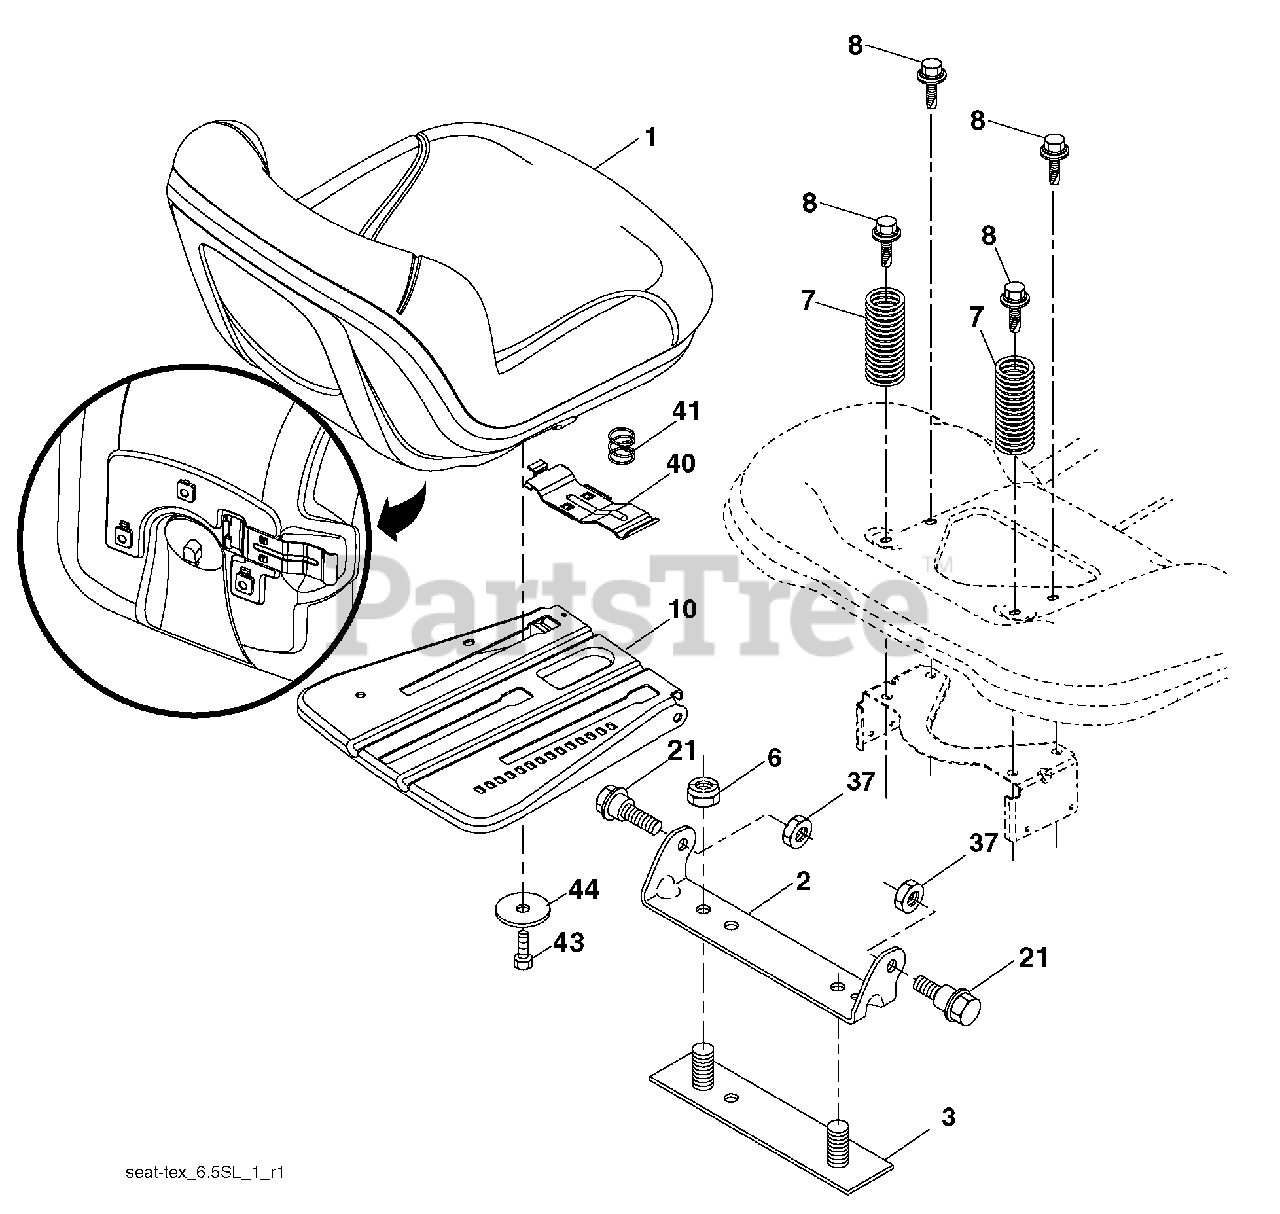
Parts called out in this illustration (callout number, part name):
1	Seat
2	Bracket Pivot Fender
3	Strap, Asm Fender
6	Nut, Lock w/Ins. 3/8-16 unc
7	Spring, Seat Cprsn
8	Bolt 5/16-18 uncx 3/4 w/Sems
10	Pan, Seat
21	Bolt, Shoulder 5/16-18
37	Nut, Lock 5/16-18 unc
40	Handle Slide Seat
41	Spring Latch Seat
43	Bolt Fin Hex 3/8-16 unc x 3/4
44	Washer 13/32 x 2-3/8 x 12Ga.
